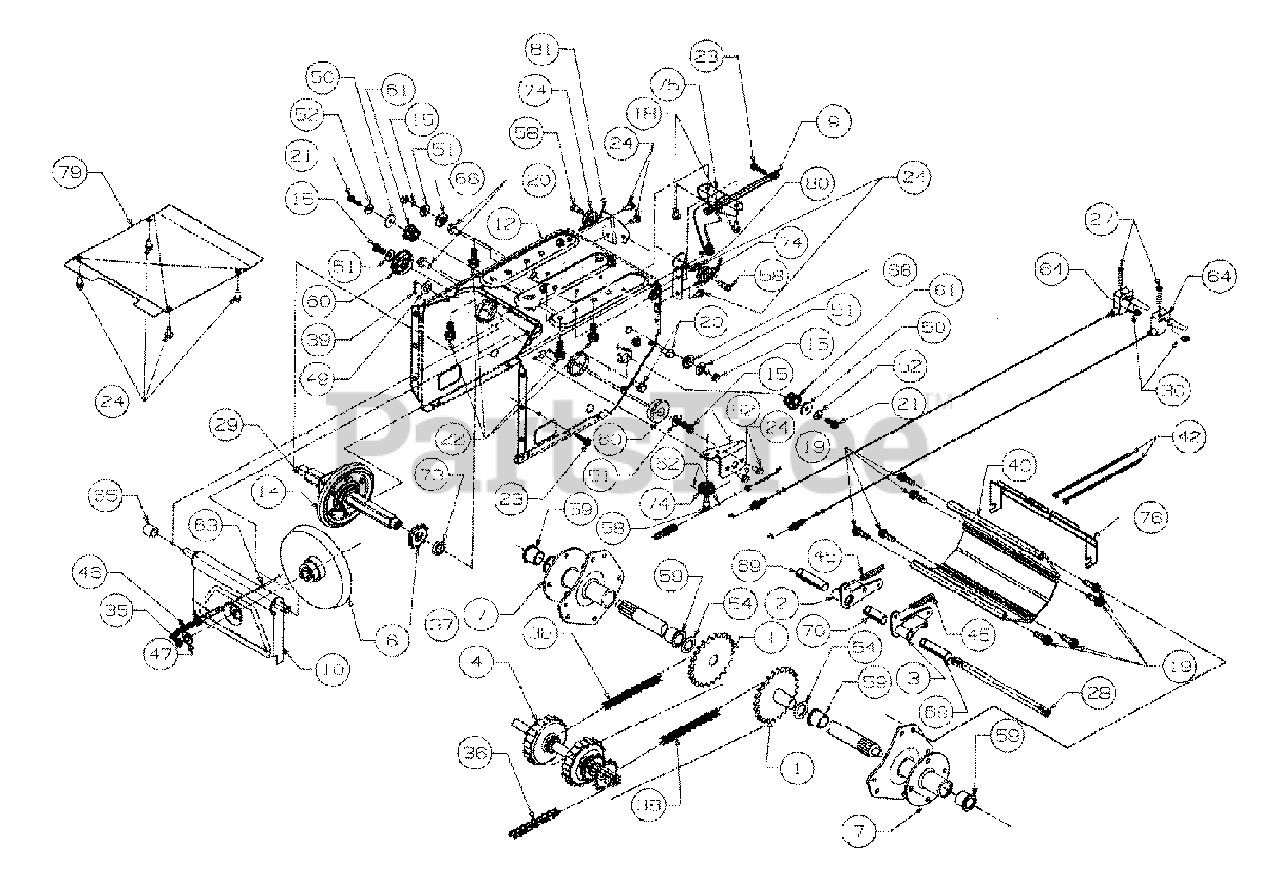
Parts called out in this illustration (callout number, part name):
1	Axle Assembly
2	Dog Assembly-R.H.
3	Dog Assembly-L.H.
4	Shaft Assembly
6	Disc Assembly
7	Hub Assembly
9	Rod Shift Assembly
10	Bracket Assembly
12	Frame Assembly
14	Wheel Assembly Friction
14	Rubber Only
15	Screw
18	Screw
19	Screw
21	Screw
23	Screw
24	Screw
27	Screw
28	Shaft
29	Shaft
30	Nut Flange
35	Nut Jam
36	Chain
37	Sprocket
38	Chain
39	Pin Cotter
40	Housing Track
42	Cable Tie
45	Spring
46	Spring
47	Washer-Bell
49	Washer-Flat
50	Washer-Flat
51	Washer-Bell
52	Washer-Bell
54	Washer-Flat
58	Screw-Shoulder
59	Bearing-Flange
60	Bearing-Ball
61	Bearing-Hex Flange
62	Cable-Auger Clutch
63	Cable-Drive Clutch
64	Cable with Trigger Lever
65	Spacer
66	Spacer-Shoulder
69	Spacer-Split
70	Spacer-Split
73	Spacer
74	Roller-Cable
79	Cover-Frame
80	Bracket-Guide
81	Bracket-Guide
82	Bracket-Guide
